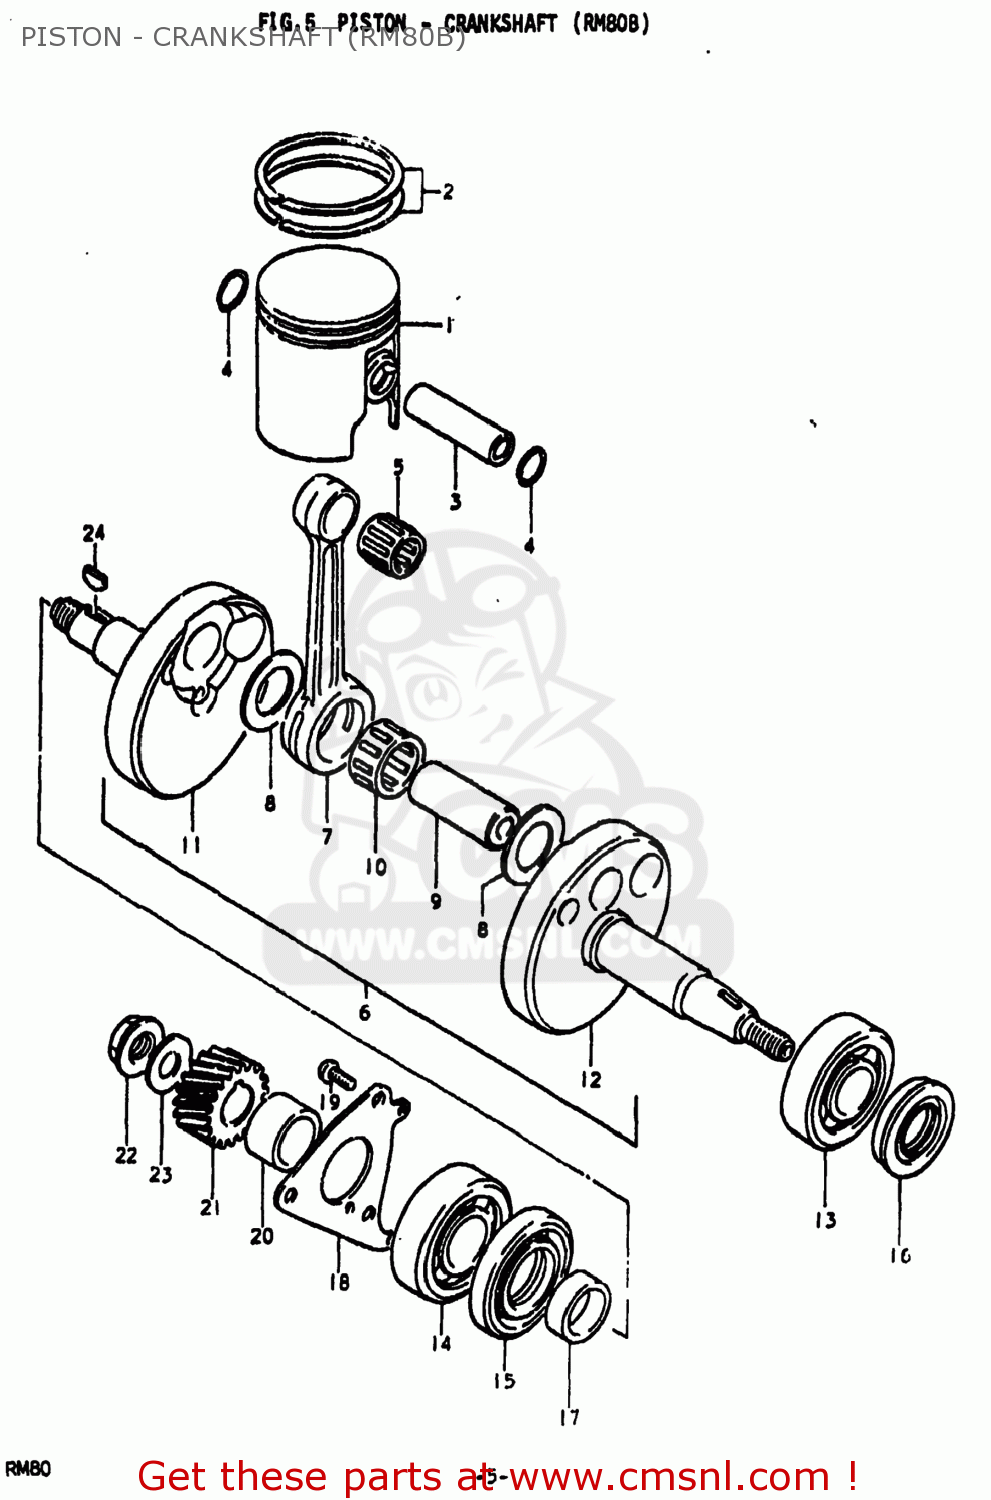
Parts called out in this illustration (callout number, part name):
1	PISTON
2	RING SET,PISTON
3	PIN,PISTON
4	RING,SNAP
5	BEARING
6	CRANKSHAFT ASSEMBLY
7	CONNECTING ROD
8	WASHER
9	PIN,CRANK
10	BEARING
11	CRANKSHAFT,RIGHT
12	CRANKSHAFT,LEFT
13	BEARING
14	BEARING
15	OIL SEAL
16	OIL SEAL
17	SPACER(20X26X9)
18	RETAINER,CRANKSHAFT BEARING,R
19	SCREW 6X12
20	SPACER(20X26X14)
21	GEAR,PRIMARY DRIVE NO.19
22	NUT
23	WASHER
24	KEY
